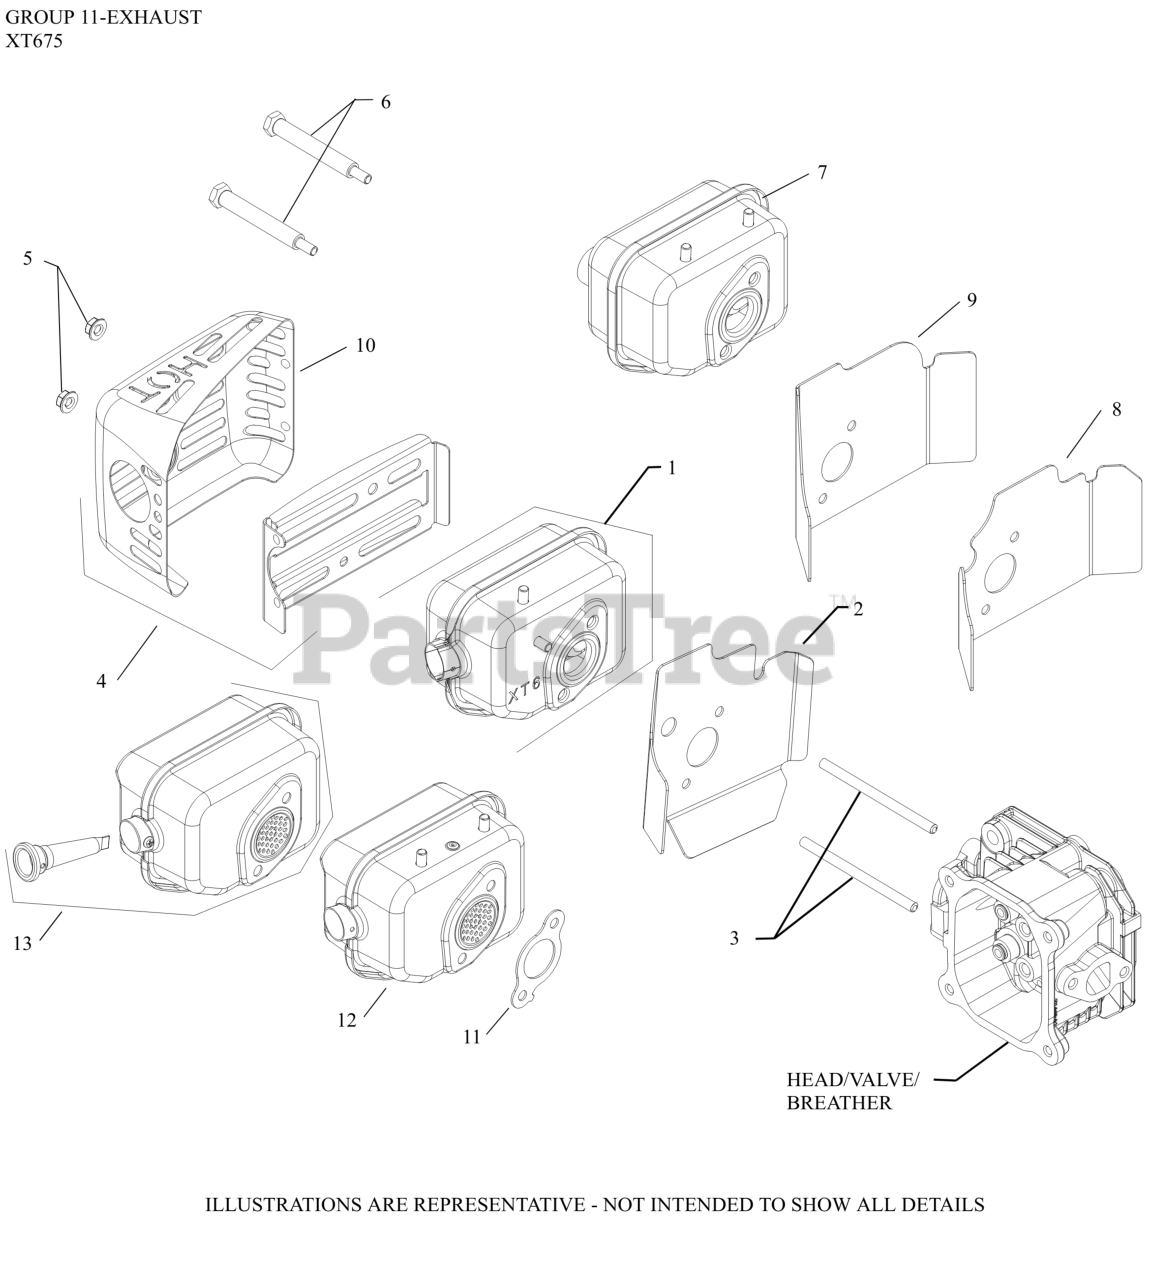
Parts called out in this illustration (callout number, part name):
1	MUFFLER ASSEMBLY-USE 14 068 35-S
4	GUARD, MUFFLER ASSEMBLY
6	SCREW, SHOULDER
NI	GUARD, MUFFLER - DISCONTINUED
